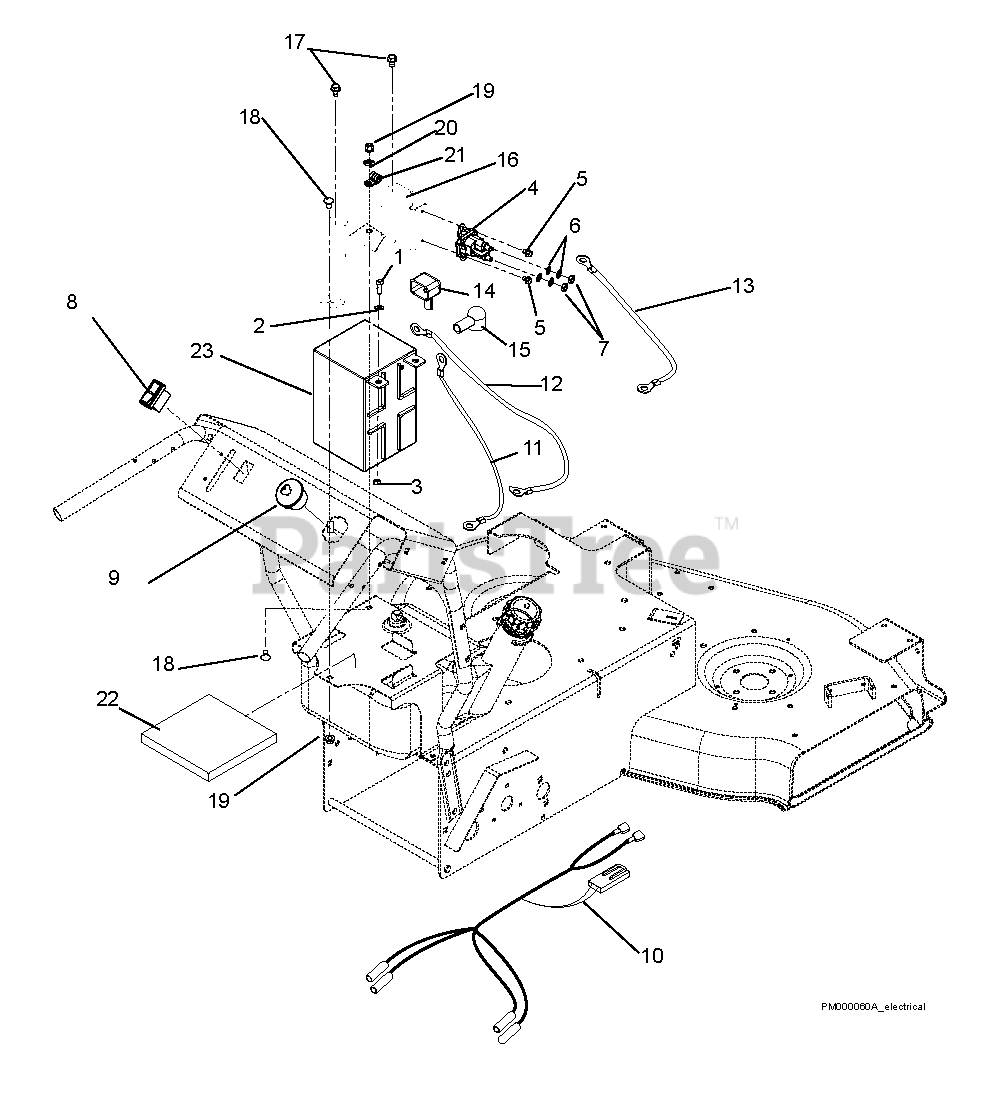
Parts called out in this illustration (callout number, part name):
1	Washer, Flat Steel .281 x .62 x .065
2	Bolt, Hex .25-20 x .75
3	Nut, KEPS .250-20
4	Solenoid
5	Screw, Tapping Hex Washer Head .250-20 x .37
6	Washer, Internal Lock .31
7	Nut, Jam .31-24
8	Switch, Rocker
9	KEYSWITCH-IGNITION 3 POS
10	Harness, Wiring
11	Cable, Positive Battery 18.50"
12	Cable, Negative 26" 6 GA.
13	Cable, POS 6.75" Bent
14	Battery, Boot
15	Battery Boot
16	Bracket, Battery Mount
17	Screw, Tapping .31-18 x .50 Hex Washer Head
18	Bolt, Round Head Square Neck .31-18 x .50 Grade 5
19	Nut, Locking-Top-Flange .31-18
20	Nut, Push .312
21	Clamp, Cushioned Steel
22	Battery Mat
23	Battery, 12V 20HR;190CCA GEP (Can be replaced with U1 battery, see Owners Manual)
